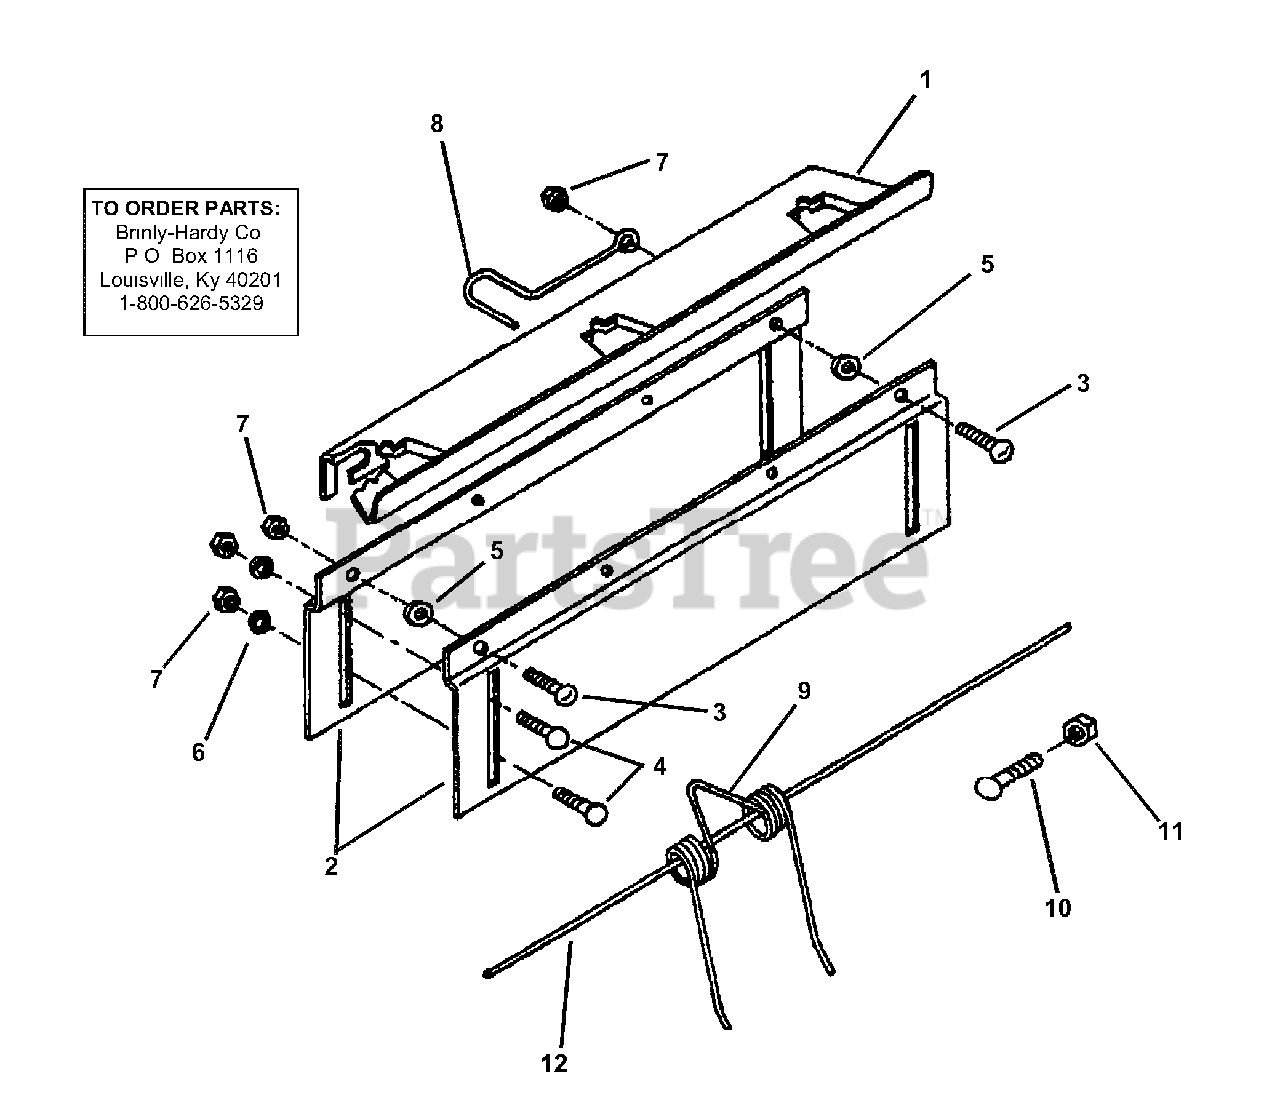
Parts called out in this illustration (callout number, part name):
1	SUPPORT, Tine
2	HOLDER, Tine Support
3	SCREW, 1/4 x 3/4" Machine
4	BOLT, 1/4 x 1" Carriage
5	SPACER
6	WASHER, 1/4" Flat
7	NUT, 1/4" Nylon Insert
8	HOOK SPRING
10	BOLT, 5/16 x 1-1/4" Carriage
11	NUT, 5/16" Hex Lock
12	SAFETY WIRE
